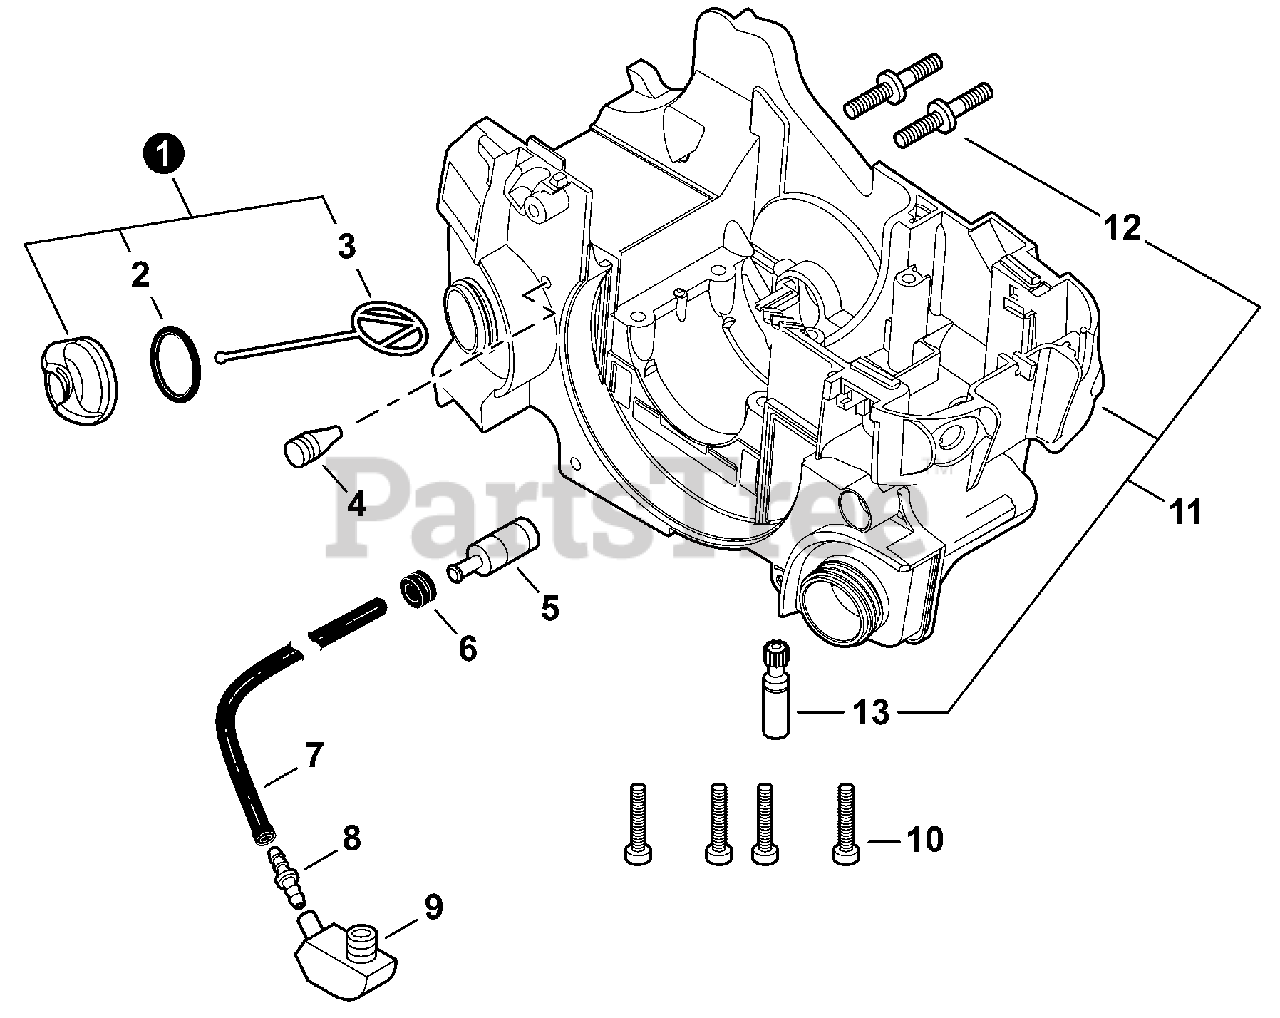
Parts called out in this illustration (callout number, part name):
1	CAP ASSY - BLACK
2	O-RING 18
3	CONNECTOR, CAP L= 60 MM
4	VENT ASSY
5	FILTER, OIL
6	GROMMET
7	PIPE 3×6×185 MM BLACK
8	CONNECTOR, PIPE
9	GROMMET, OIL
10	BOLT, TORX 5×30
11	HOUSING ASSY, ENGINE
12	BOLT, STUD 8
13	AUTO-OILER ASSY
